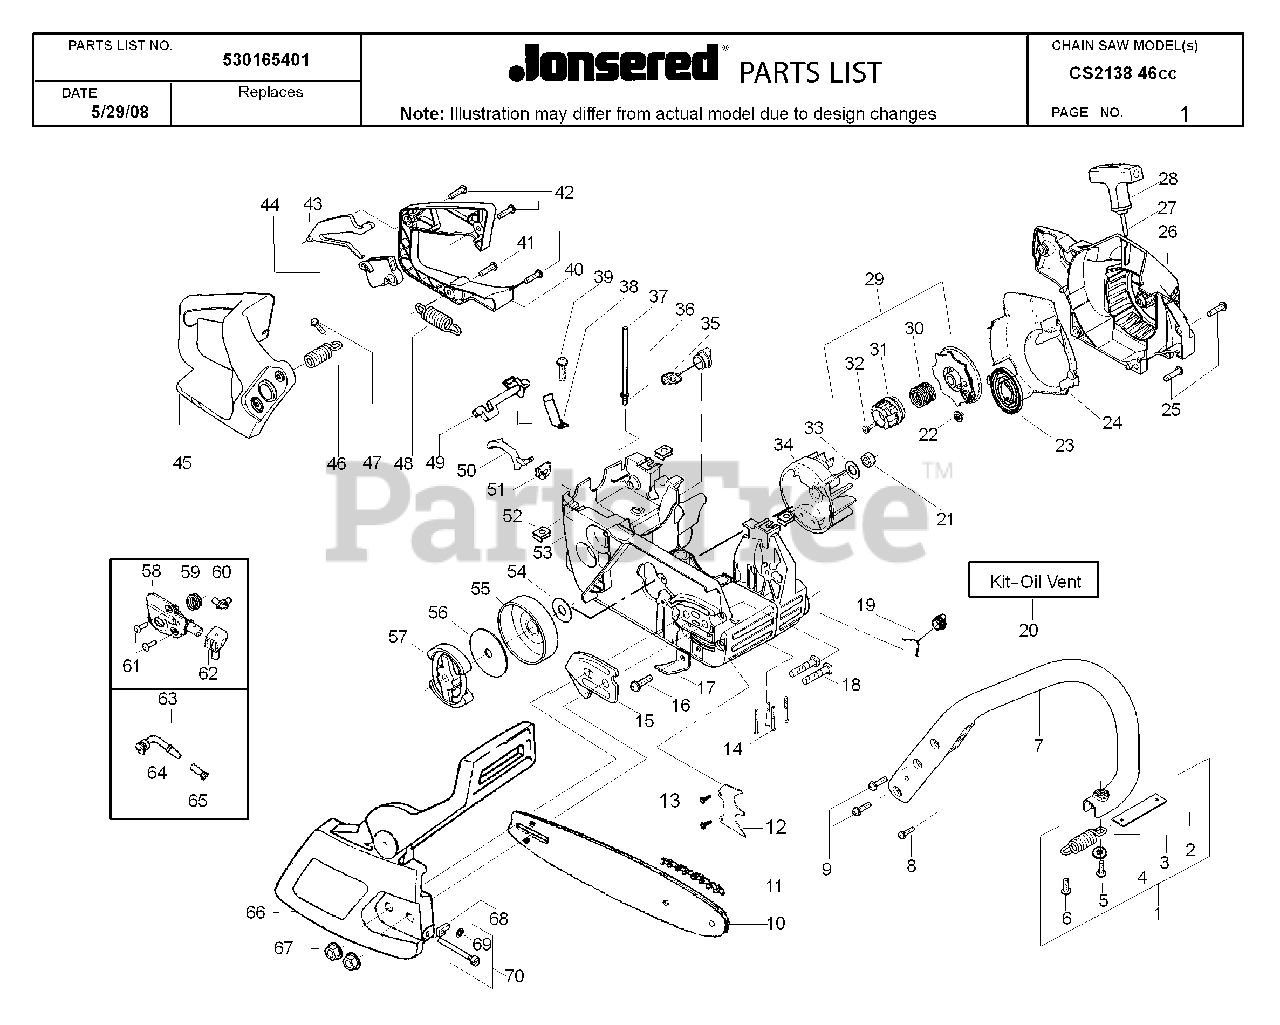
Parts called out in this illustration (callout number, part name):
2	STRAP
3	SPRING ISOLATOR
4	WASHER
12	SPIKE 36/41
17	CHAIN CATCHER 36/41
19	OIL TANK CAP
20	KIT-OIL CHECK VALVE
21	NUT-FLYWHEEL
24	AIR BAFFLE
25	SCREW,STRTR CVR 36/41
28	HANDLE STARTER
29	KIT EPS STARTER
30	SPRING EPS
31	HUB STARTER EPS
32	SCREW SHOULDER
33	WASHER-FLYWHEEL
35	TANK CAP
36	FUEL LINE FITTING
38	SPRING-SWITCH
39	SCREW 8-16 X 9/16 (PLAS
41	SCREW-10-14 X 13/16 (PL
42	SCREW,FRONT HBAR 36/41
43	THROTTLE LOCK
44	THROTTLE TRIGGER
46	SPRING
48	SPRING ISOLATOR
49	LEVER-SWITCH
50	LEVER-CHOKE
54	DUST COVER 36/41
55	CLUTCH DRUM ASSY
56	FRICTION DISC,CLUTCH 36/41
57	CLUTCH ASSEMBLY
59	WORM GEAR
64	PICK-UP OILER
65	SCREEN/FILTER
68	ADJUST PIN,BAR 36/41
